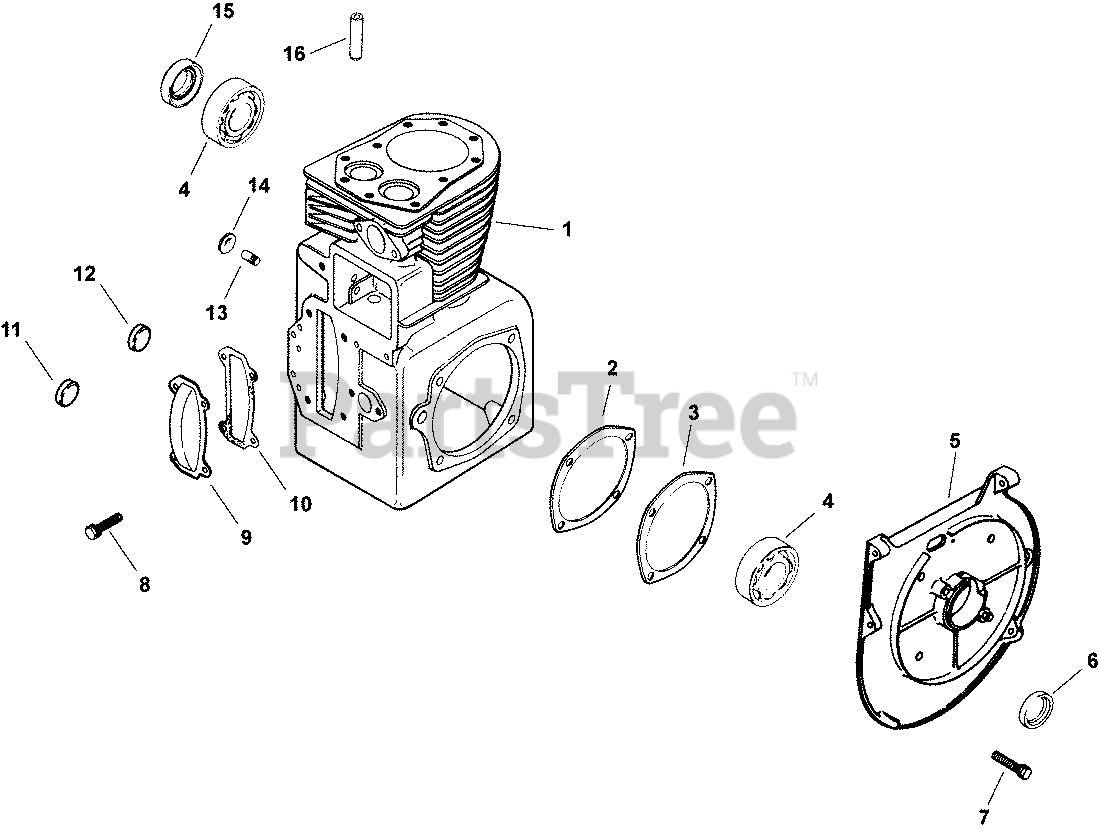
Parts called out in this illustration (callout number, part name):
1	CRANKCASE ( USE: MINI BLOCK)
3	GASKET, BEARING PLATE - DISCONTINUED
4	BEARING, BALL
5	PLATE, BEARING - DISCONTINUED
6	SEAL, FRONT OIL
7	SCREW, SEMS 3/8-16-X1"
8	SCREW, SEMS 1/4-20-1/2"
9	COVER, CAMSHAFT - DISCONTINUED
10	GASKET, CAMSHAFT COVER
11	PLUG, CUP
12	PLUG, CUP 1/2"
13	SHAFT, GOVERNOR GEAR
14	PLUG, WELCH EXPANSION
15	SEAL, REAR OIL
16	GUIDE, VALVE - DISCONTINUED
